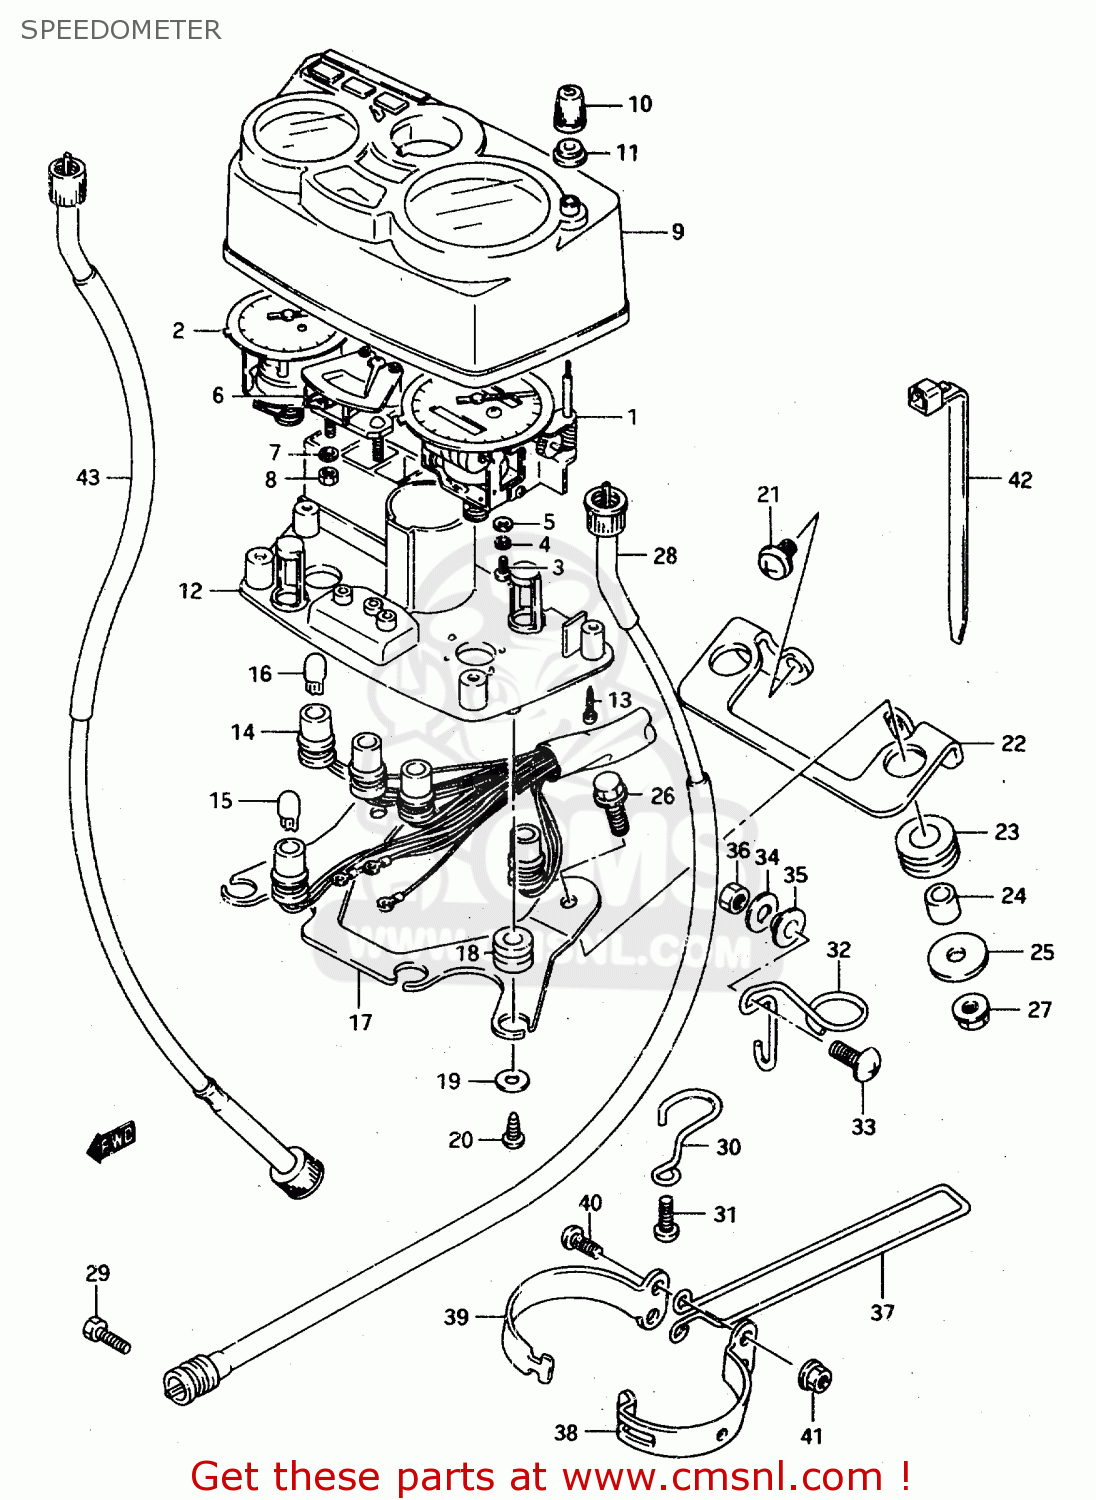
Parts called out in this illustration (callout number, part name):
1	SPEEDOMETER
2	TACHOMETER
3	SCREW
4	LOCK WASHER
5	WASHER 3.3X8X0
6	GAUGE,WATER TEMPERATURE
7	LOCK WASHER
8	NUT
9	HOOD, METER
10	KNOB,TRIP METER
11	SEAL,TRIP KNOB
12	CASE,METER
13	SCREW
14	SOCKET,METER
15	BULB(12V3.4W,T10,BF175-01450A)
16	BULB(12V1.7W,T10,WB121)
17	BRACKET,METER
18	CUSHION
19	WASHER
20	SCREW
21	SCREW
22	BRACKET, SPEEDOMETER
23	CUSHION
24	SPACER(6.5X11.5X12)
25	WASHER (6.5X24X1.6)
26	BOLT
27	NUT
28	CABLE ASSY,SPEEDOMETER
29	BOLT
30	GUIDE,SPEEDOMETER CABLE
31	SCREW
32	GUIDE, CABLE NO.2
33	SCREW
34	WASHER
35	WASHER
36	NUT
37	GUIDE, CABLE NO.3
38	BRACKET,CABLE GUIDE
39	BRACKET,CABLE GUIDE
40	SCREW
41	NUT
42	CLAMP(L:125)
43	CABLE ASSY, TACHOMETER
